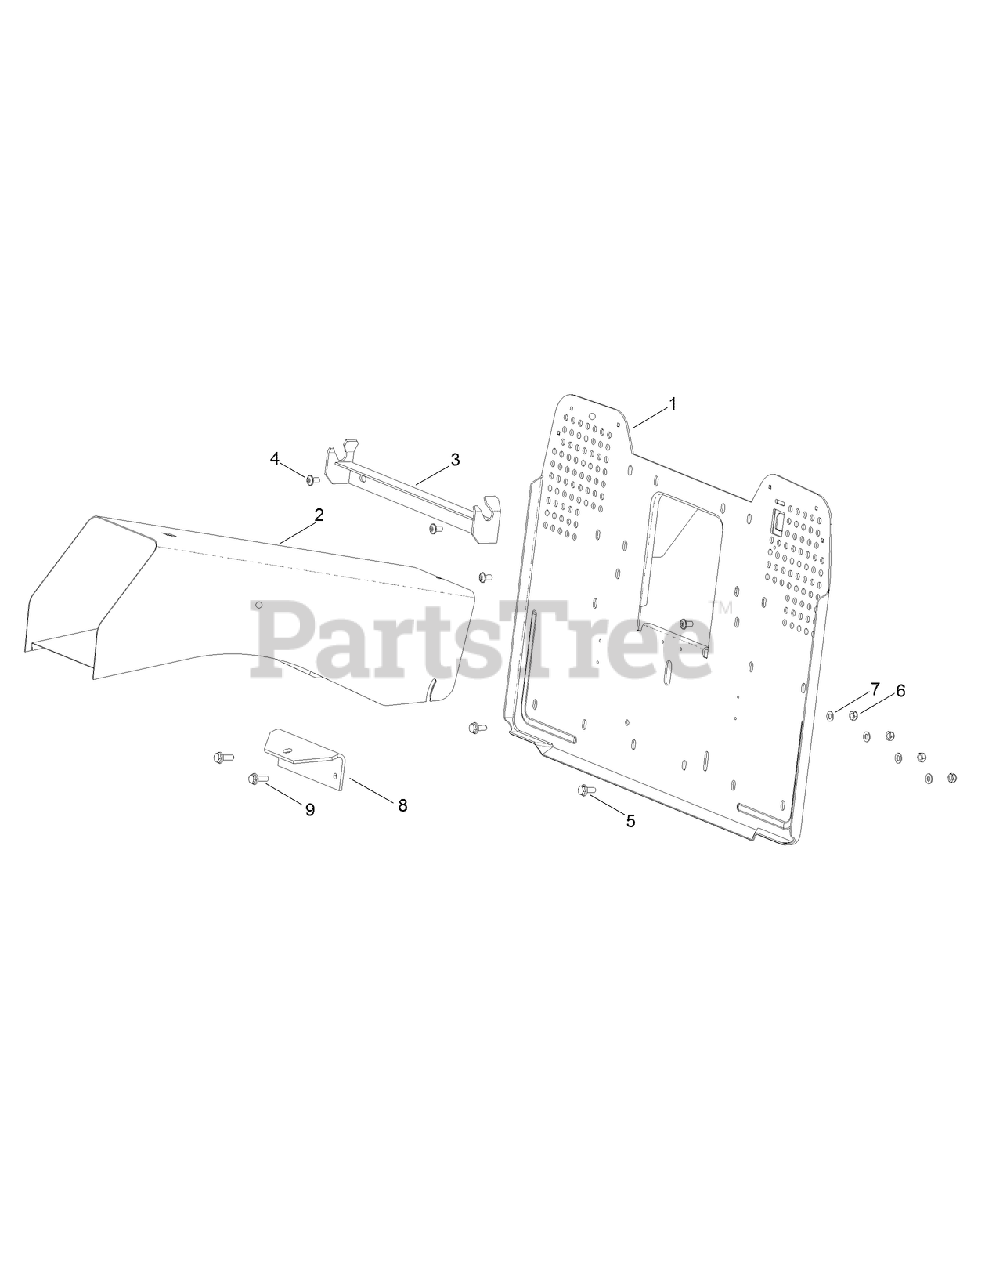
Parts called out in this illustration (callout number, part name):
1	COLLECTOR PLATE ASM
2	TUNNEL
3	SUPPORT-COLLECTOR
4	BOLT-CARRIAGE
6	NUT-LOCK, NI
7	WASHER-PLAIN
8	HITCH-TOW
9	SCREW-HHF
